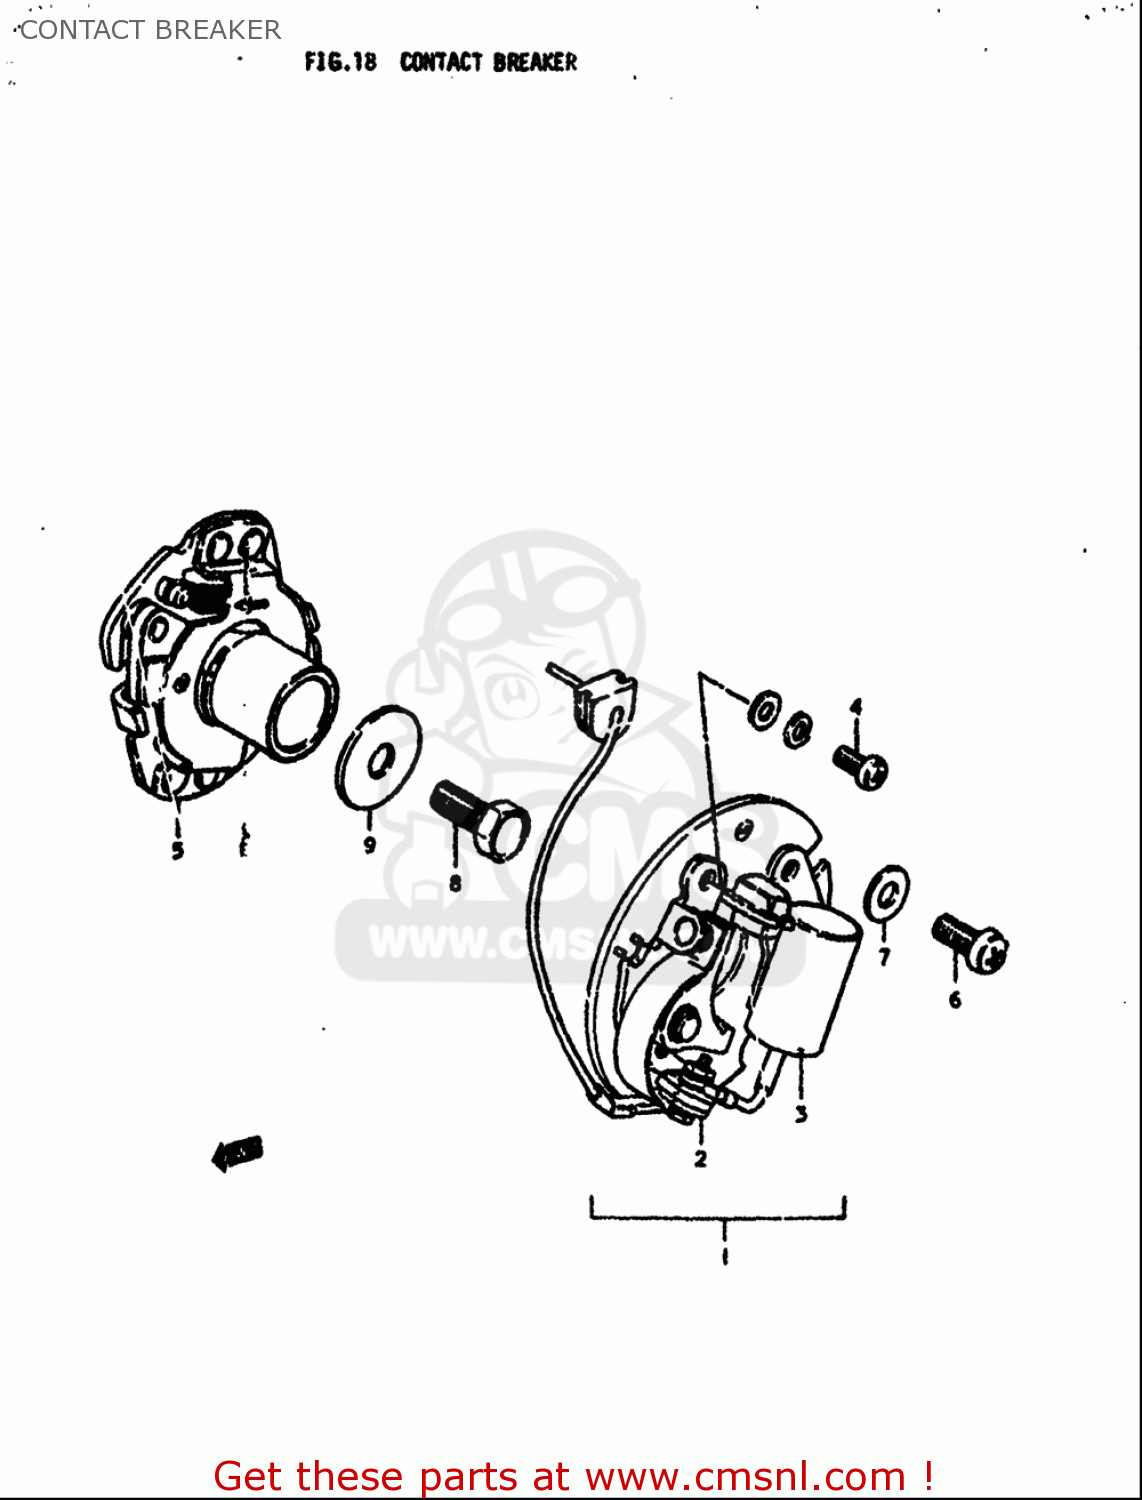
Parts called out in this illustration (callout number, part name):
2	POINT ASSY,CONTACT
3	CONDENSER
4	SCREW 4X6
6	SCREW(5X12)
7	WASHER
8	BOLT
